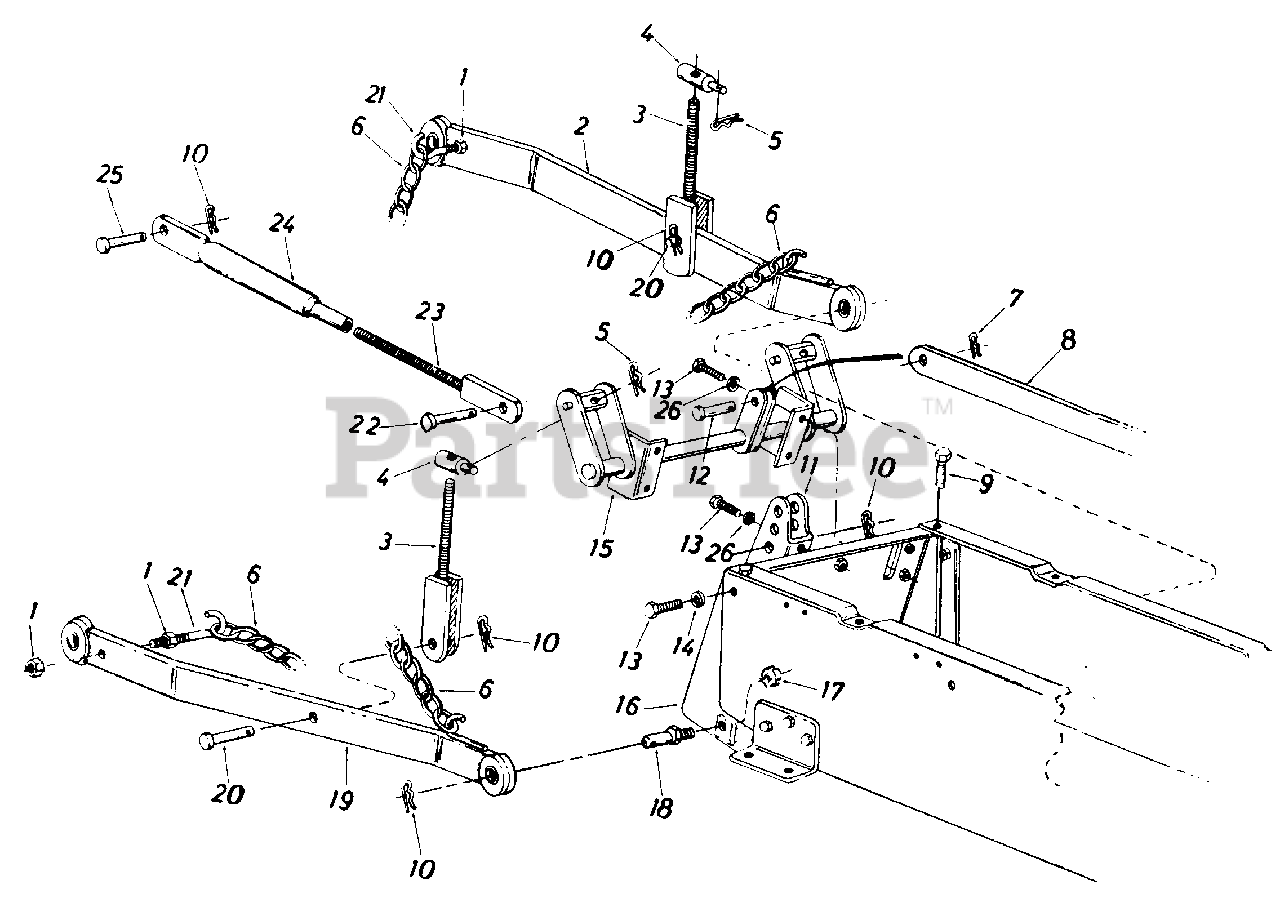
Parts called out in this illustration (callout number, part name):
1	Hex Cent. L-Nut 7/16-14 Thd.
2	Draft Bar Ass'y. L.H.
3	Clevis Screw Ass'y.
4	Clevis Pin
5	Hitch Pin Clip
6	Chain 20 Links
7	Cotter Pin 1/8" Dia. x 1.25" Lg.*
10	Hairpin Cotter
12	Clevis Pin
13	Hex Scr. 3/8-16 x .75" Lg.
14	L-Wash. 3/8" Scr. H.D.
18	Link Clevis Pin
19	Draft Bar Ass'y. R.H.
20	Clevis Pin .63 Dia. x 1 .66" Lg.
21	Hitch Chain Hook
22	Clevis Pin .63 Dia. x 2 4" Lg.
23	Clevis Screw
25	Clevis Pin .63 Dia. x 2.4" Lg.
26	L-Wash. 3/8" Scr. H.D.
